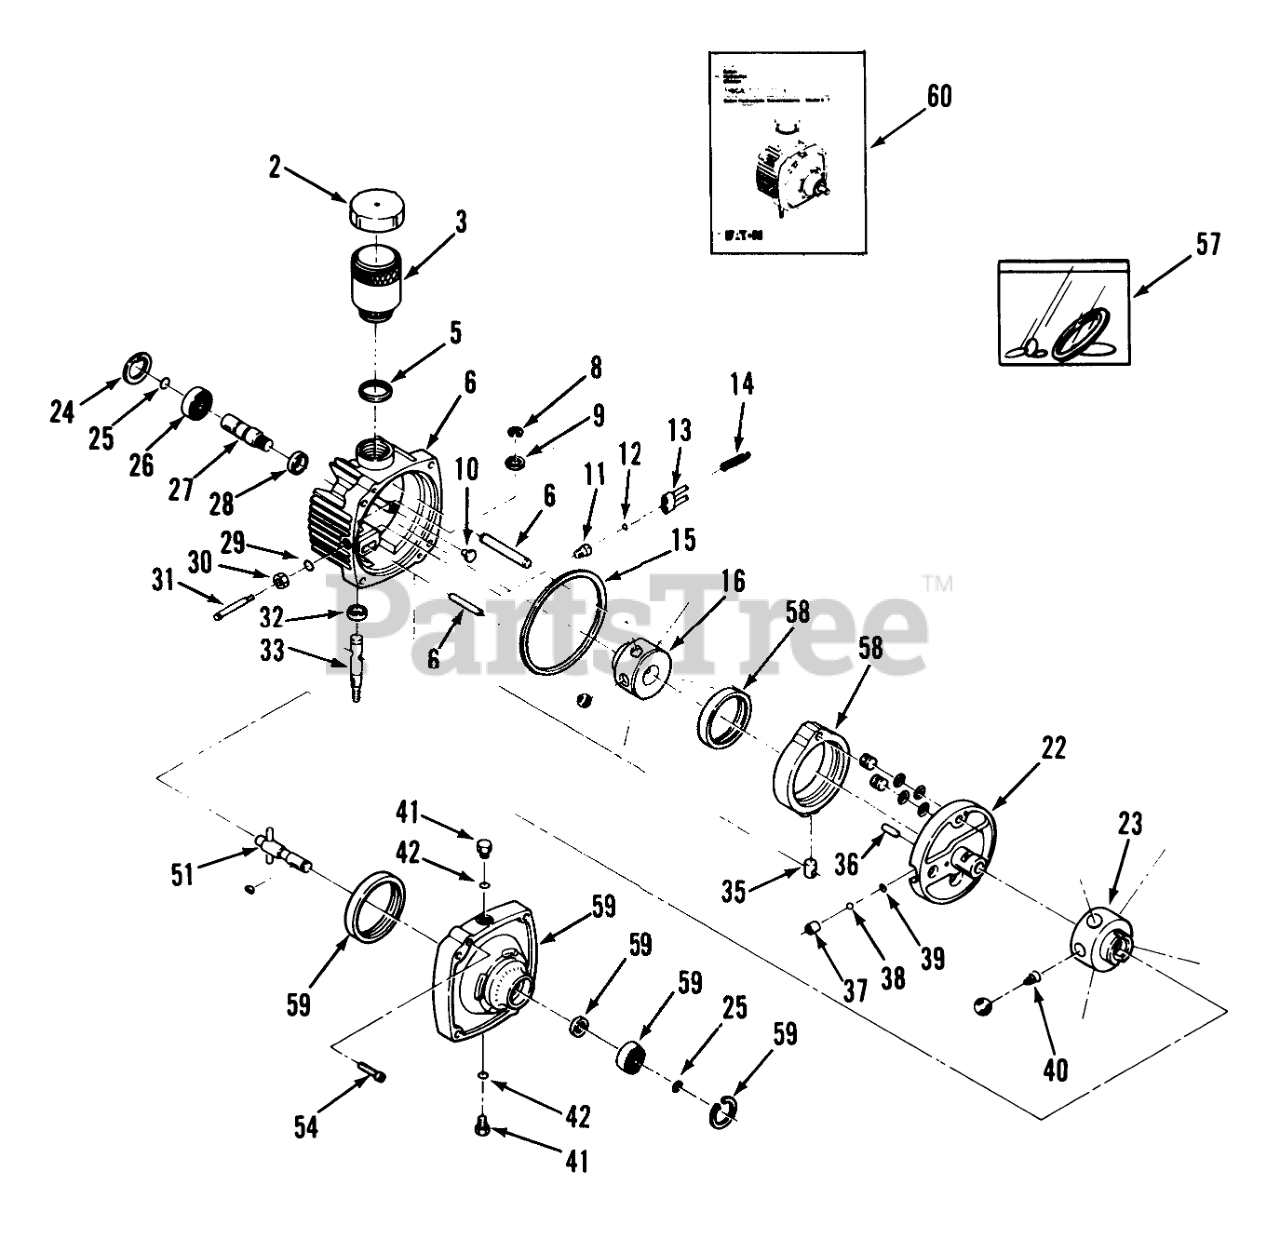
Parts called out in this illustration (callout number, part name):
2	RESERVOIR COVER
3	BODY-RESERVOIR
5	Seal-Ring, Sq (Incl. Item 57)
6	Kit-Cover Service (Incl. Items #8, 9, 28, 32 & 33)
8	Ring-External Retaining (Incl. Item #6)
9	Washer-Control Shaft (Incl. Item #6)
10	Button
11	Fitting-Guide Assembly, O-Ring (Incl. Item #12)
12	Valve-Bracket (Incl. Items #11 & 57)
13	SUB-ASS'Y BRACKET
14	SPRING-VALVE
15	Seal-Ring, Sq (Incl. Item #57)
16	SUB-ASS'Y PUMP ROTOR
22	Pintle Assembly-Used in CCW rotation trans. Model #00700-023 (Incl. Items #36, 37, 38, & 39)
23	SUB-ASS'Y MOTOR
24	Retaining Ring
25	SNAP-RING
26	BEARING-BALL (INPUT)
27	SHAFT-INPUT
28	Seal-Oil (Incl. in Items #6 & 57)
29	O-Ring-Dump Valve (Incl. Item #57)
30	Gasket Assembly (Incl. Item #57)
31	PULLEY FLAT B
32	Seal-Oil (Incl. in Items #6 & 57)
33	Kit-Control Shaft (Incl. in Item #6)
35	INSERT-CAM RING
36	Pin-Coil (Incl. Item #22)
37	Body-Check Valve (Incl. Item #22)
38	Ball-Grade 200 5/16 O.D. (Incl. Item #22)
39	Ring-Retaining (Incl. Item #22)
40	Spring-Piston (Incl. Item #23)
41	Plug Assembly-O-Ring (Incl. Item 42)
42	O-Ring-Tube Fitting (Incl. Items #41 & 57)
51	Shaft Assembly-Output (Incl. Item #59)
54	Screw
57	Kit-Overhaul Sealing (Incl. Items #5, 11, 12, 15, 28, 29, 30, 32, & 42)
58	Ring Sub-Assembly-Cam (Incl. Pump Race & Cam Ring)
59	Body Assembly (Incl. Body, Oil Seal, Output Ball Bearing, Snap Ring, Retaining Ring, Motor Race, & Item #51)
60	Hydrostatic Transmission Repair Manual
